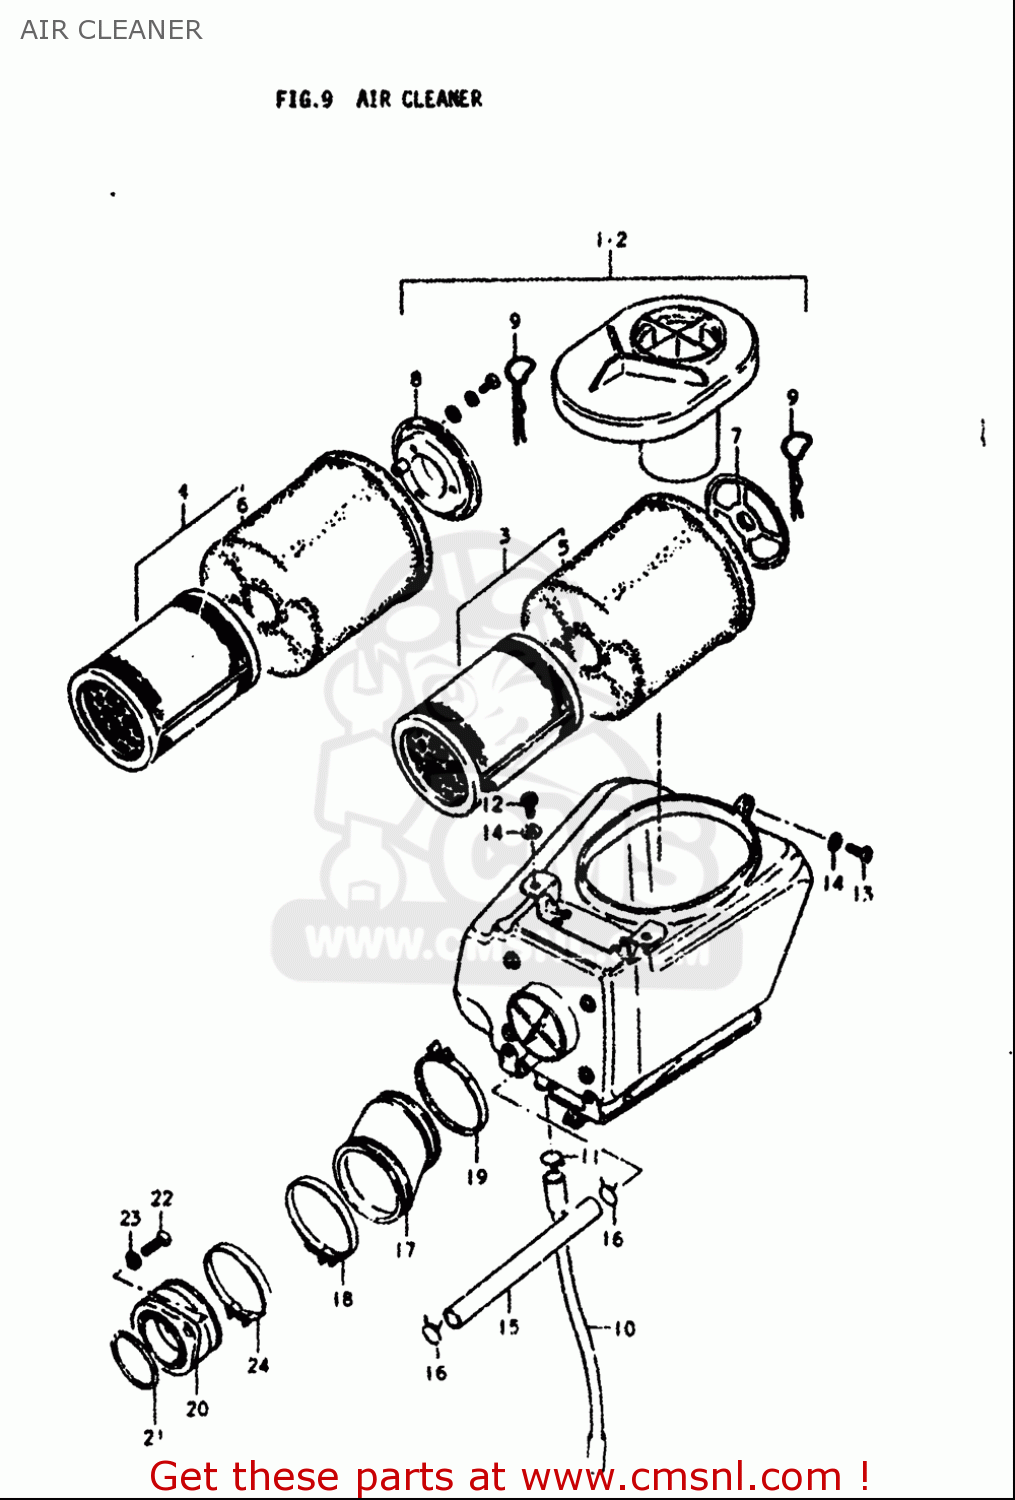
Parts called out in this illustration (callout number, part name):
3	FILTER,AIR CLEANER
4	FILTER,AIR CLEANER
6	ELEMENT,AIR CLEANER
11	CLIP
12	SCREW
13	SCREW
14	WASHER
16	CLIP
17	TUBE,AIR CLEANER OUTLET
18	CLAMP
19	CLAMP
20	PIPE,INTAKE
21	O RING(D:2.4,ID:39.7)
22	SCREW
23	WASHER,LOCK
24	CLAMP
